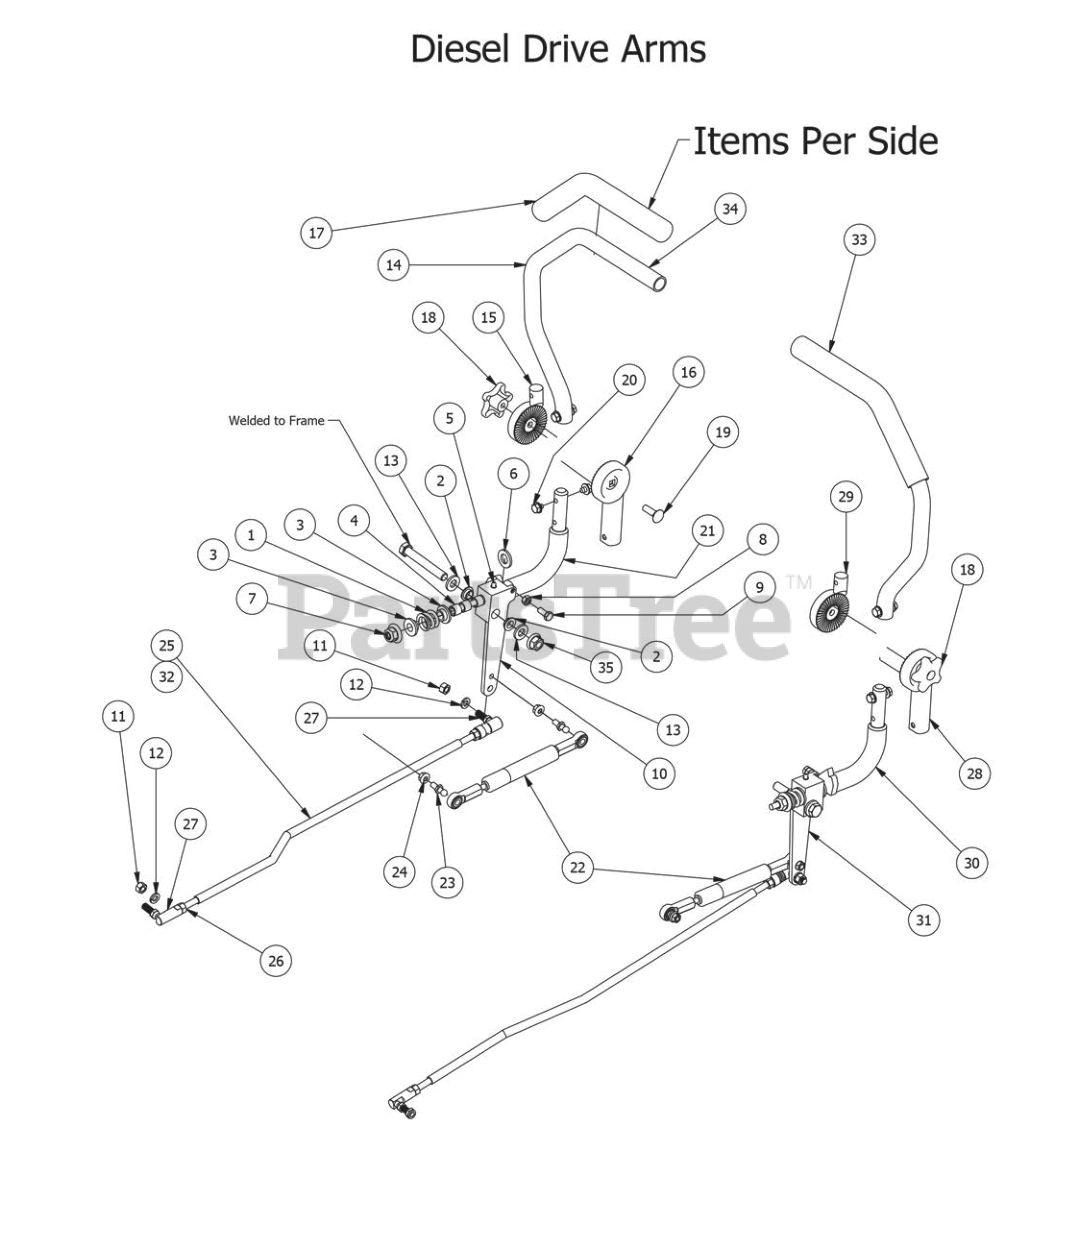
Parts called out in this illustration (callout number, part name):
1	Drive Lever Spring
2	Bushing for 2012 Drive Arms
3	.515 ID Nylon Shoulder Washer
4	.507 ID Nylon Bushing
5	1/4" Drive in Grease Fitting
6	.635 ID Plastic Washer
7	1/2-13 Nylon Flange Nut-Orange
9	5/16" x 3/4" Hex Bolt
10	Drive Arm Lever Housing (Left)
11	3/8" Fine Threaded Jam Nut
12	3/8" Lock Washer
13	.505x1x.125 Oil Impregnated washer
14	Upper Tube-Adjustable Steering
15	Upper adjuster-Steering Arm- Left
16	Lower Adjuster - Steering Arm- Left
17	Black Steering Grip
18	Black Knob for Adjustable Steering Arm
19	3/8" x 1 1/4" Carriage Bolt
20	5/16-18 1/2 HWH Bolt-Steering
21	Steering Arm Elbow - Left
23	10mm Damper Ball Stud-Steering
24	5/16" Flange Nut
25	Streering Push Rod - 28Hp Diesel Push Rod
26	3/8" Fine Threaded Jam Nut
27	3/8-24 Ball Joint
28	Lower Adjuster -Steering Arm- Right
29	Upper Adjust Steering Arm- Right
30	Steering Arm Elbow - Right
31	Drive Arm Lever Housing Right
32	Steering Push Rod -35HP Diesel
33	Adjustable Steering Arm-Right Assembly-Componets 14,17,18,19,20,28,29
34	Adjustable Steering Arm-Left Assembly-Componets 14,15,16,17,18,19,20
35	1/2-13 Hex Flange (GR.G) ZC
